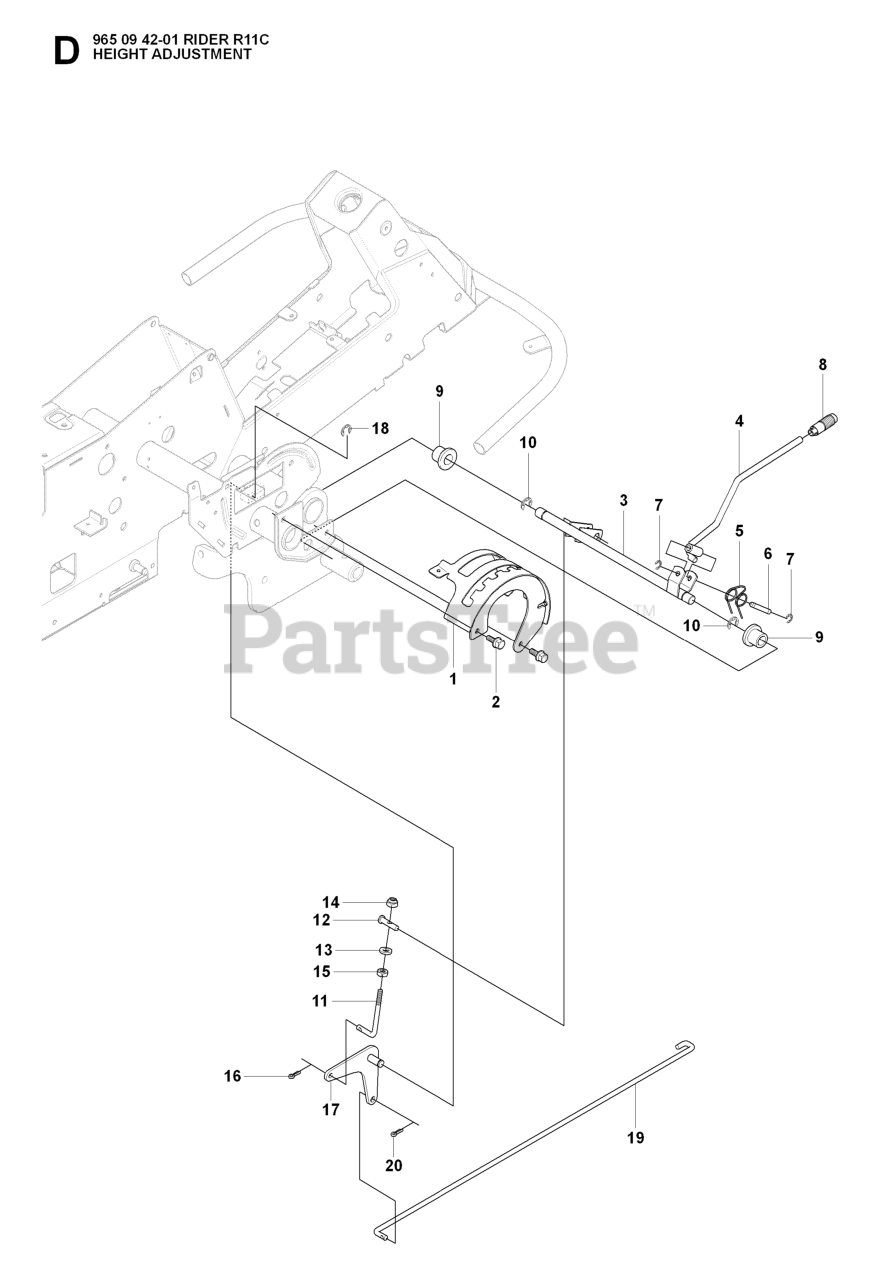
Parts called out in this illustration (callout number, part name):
1	CONTROL PLATE
3	HEIGHT ADJUSTER
4	HEIGHT ADJUSTER
5	HAIR PIN SPRING
8	GEAR STICK KNOB
9	BUSHING
13	WASHER
14	LOCKNUT M8
15	NUT
17	LINK HEIGHT ADJUSTMENT
18	RETAINING RING
19	CONNECTION ROD
